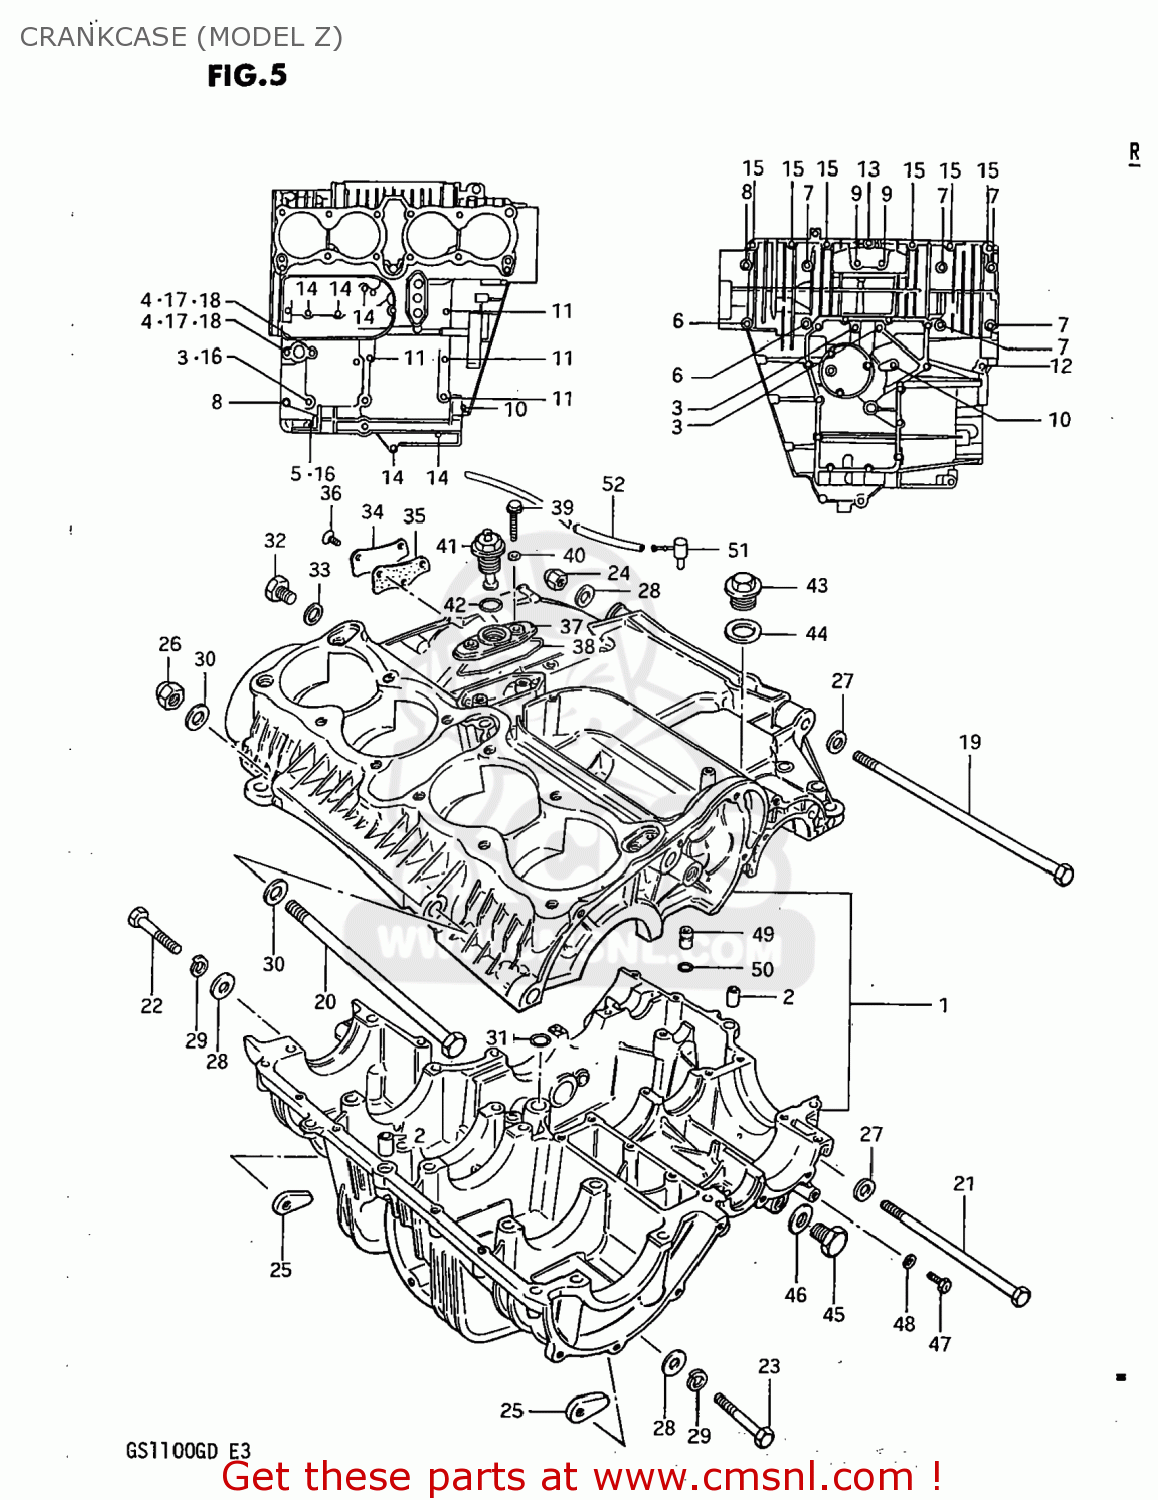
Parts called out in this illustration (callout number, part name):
1	CRANKCASE SET
2	PIN
3	BOLT
4	BOLT
5	BOLT
6	BOLT
7	BOLT 8X90
8	BOLT 8X65
9	BOLT
10	BOLT (6X90)
11	BOLT (6X75)
12	BOLT
13	BOLT ,6X50
14	BOLT,UNDER
15	BOLT 6X35
16	NUT
17	NUT
18	GASKET 8.2X14X1 (NAS)
19	BOLT 10X270
20	SHAFT,REAR SWING ARM
21	BOLT(10X165)
22	BOLT 10X60
23	BOLT (10X50)
24	NUT
25	NUT
26	NUT 12MM
27	WASHER(10.5X20X3.2)
28	WASHER
29	LOCK WASHER
30	WASHER
31	O RING(D:3.2,ID:12.9)
32	PLUG (14X12)
33	GASKET(14X19.2X2) (NAS)
34	CAP,OIL GALLERY
35	GASKET,OIL GALLERY (MCA)
36	SCREW
37	HOUSING,OIL PRESSURE SWITCH
38	O RING,PRESSURE SWITCH HOUSING
39	BOLT
40	GASKET (NAS)
41	SWITCH ASSEMBLY
42	O RING(D:1.9,ID:18.8)
43	PLUG
44	GASKET
45	PLUG
46	GASKET(14X19.2X2) (NAS)
47	SCREW(6X10)
48	GASKET (NAS)
49	UNION
50	O RING(D:1.05,ID:3.1)
51	BPLUG,BEVEL GEAR BREATHER
52	HOSE
